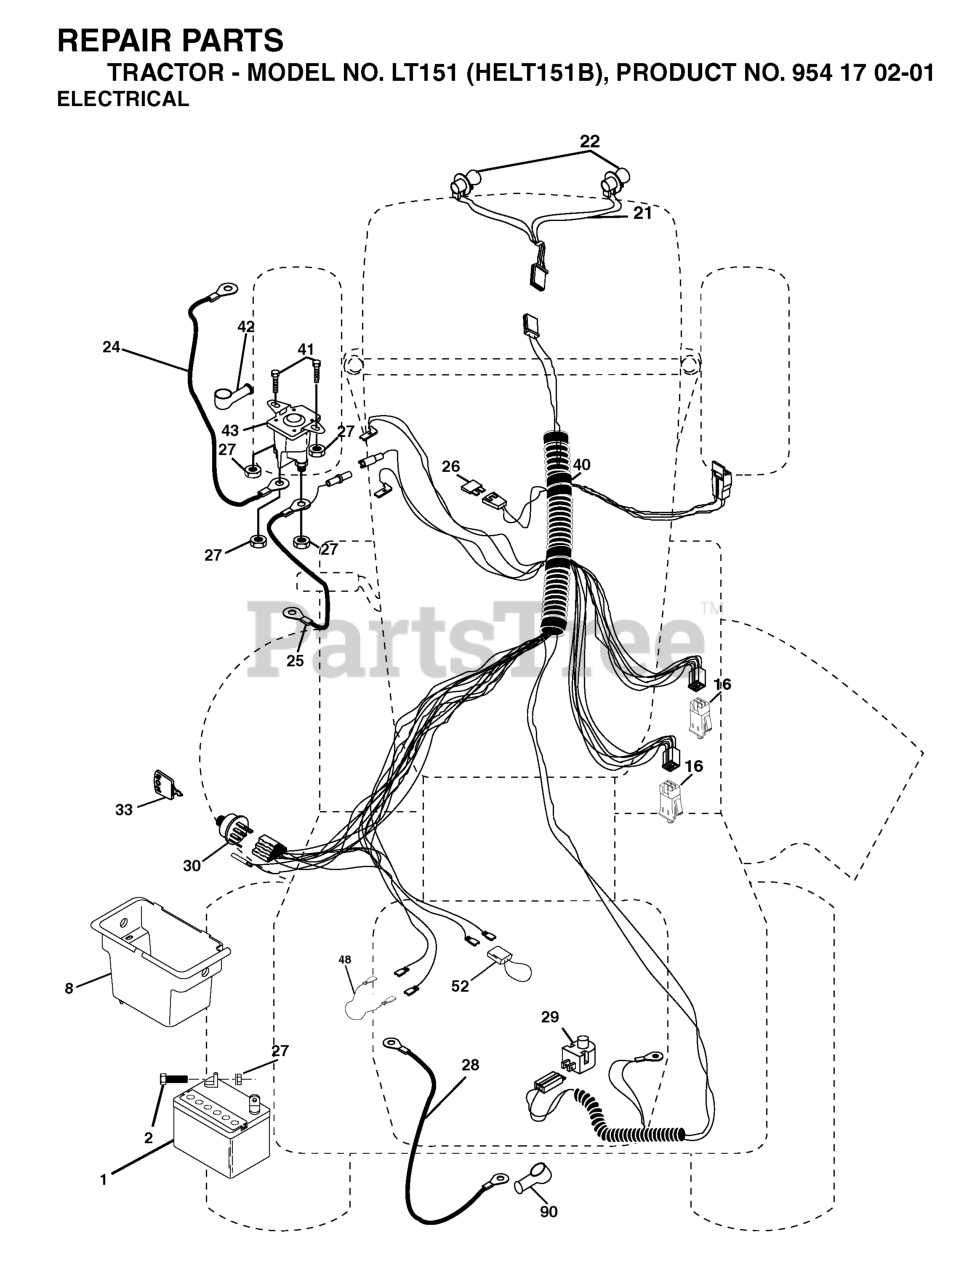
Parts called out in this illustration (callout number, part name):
1	BATTERY 12V .35 AMP
2	BOLT.HEX.1/4.X.3/4.DICHROMATE
8	BOX.BATTERY.FENDER
16	SWITCH INTERLOOK PUSH-IN
21	HARNESS.W/LIGHT SOCKET
24	BATTERY CABLE GT
25	CABLE BATTERY
26	FUSE 20AMP
27	NUT
28	CABLE T
29	RP.SWITCH.PLUNGER.NC.GRAY
30	IGNITION SWITCH
33	KEY MLD GEN DELTA
40	HARNESS.IGNITION
41	BOLT
42	TERMINAL COVER
43	SOLENOID
48	ADAPTER.AMMETER
52	WIRE PROTECTION LOOP
90	COVER TERMINAL
